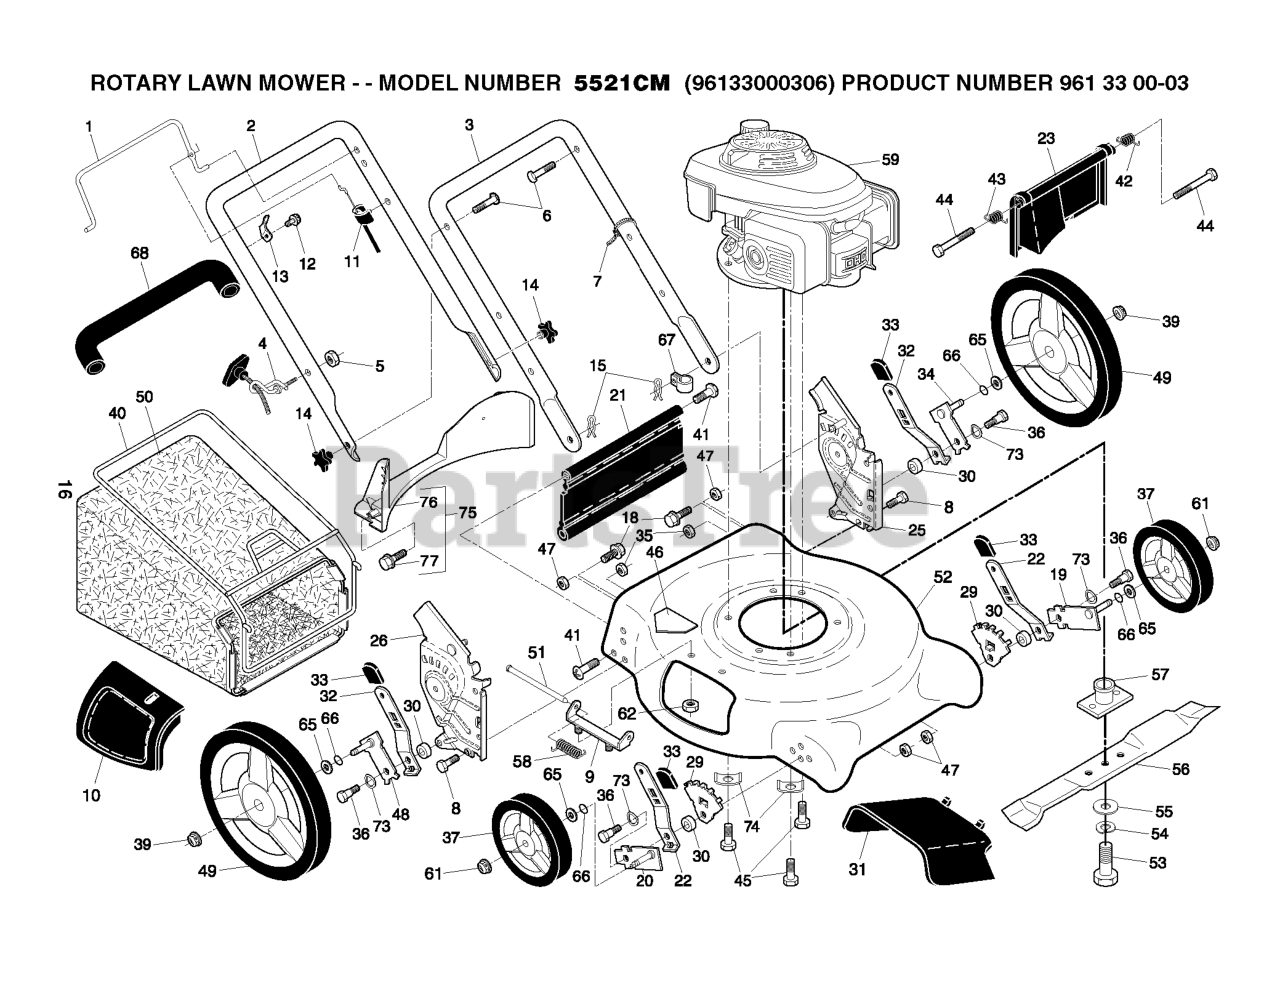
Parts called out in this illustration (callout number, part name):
1	BAIL.MZR.STD.ORANGE
2	UPPERHANDLE(INCLUDES FOAMGRIP)
3	HANDLE.LOWER.GREY
4	RB GUIDE.ROPE.STD.BLK.ZIN WSL
5	NUT
6	BOLT, HANDLE 5/16-18X1.75
7	TIE GUIDE
8	BOLT.FIN.HEX.5/16-18X3/4
9	BRACKET.ASM.HOUSING.EZ.MUL
10	RP DOOR.MULCH.21".REAR.PUSH.GR
11	ENGINE ZONE CONTROL CABLE
13	BRACKET
14	KNOB.HANDLE.STAR.HUSQ.GRAY
15	HAIRPIN COTTER
18	SCREW 1/4X20
19	AXLE ARM ASSY FRONT LH
20	AXLE ARM ASSY FRONT RH
21	RP_KIT.SKIRT.21 DOMED.W/LIP
22	SELECTOR SPRING, FRONT
23	REAR DOOR ASSY
25	RP BRKT.ASM.HAND.HW.21.LT.ORNG
26	RP BRKT.ASM.HAND.HW.21RT.ORNG
29	WHEEL ADJ BRACKET FRONT
30	SPACER.HEIGHT.ADJUSTER
31	DEFLECTOR.CLIPPING.21.GREY
32	SPRING.SEL.EXT.21.DOMED.12/14
33	SELECTOR KNOB
34	AXLE ARM ASSY REAR LH
35	NUT.LOCK.5/16-18
36	SHOULDER BOLT 5/16-18
37	WHEEL & TIRES ASSY, FRONT
39	NUT.HEX.FLANGE.3/8-16.LOCKNUT
40	FRAME.BAG.21.REAR.DOMED.PUSH
41	HINGE SCREW
42	SPRING.LH.22.REAR.DOOR.EZ.EMPT
43	SPRING.RH.22.REAR.DOOR.EZ.
45	BOLT 3/8-16X1-1/8
46	DANGER DECAL
47	LOCKNUT 5/16-18
48	AXLE ARM ASSY REAR RH
49	WHEEL ASSY
50	GBAG.24710247.SILVER.H
51	ROD.HINGE.COMBI-C
52	KIT, LAWN MOWER HOUSING ASSY
53	SCREW, HEX HD 3/8-24 X 1-3/8
54	LOCKWASHER
55	WASHER,HARDEN
56	BLADE.21.PUSH/RWGD/FWGD
57	ADAPTER.BLADE
58	TORSION SPRING
61	NUT.HEX.FLANGE.3/8-16.LO(3 2)
62	LOCKNUT.NYLOC.1/4-20
65	WASHER.FLAT.1/2
66	O-RING..070X.487.NEOPRENE
67	CLIP.CABLE.BLK
68	GRIP.HANDLE.FOAM
73	WASHER.CURVED.CYLINDRICAL
74	WASHER.ENGINE.BZP
75	KIT.BAFFLE.REAR.PLASTIC.21.RD
76	BAFFLE.REAR.PLASTIC.21.RD.ECON
77	SCREW.HX.13X.750
